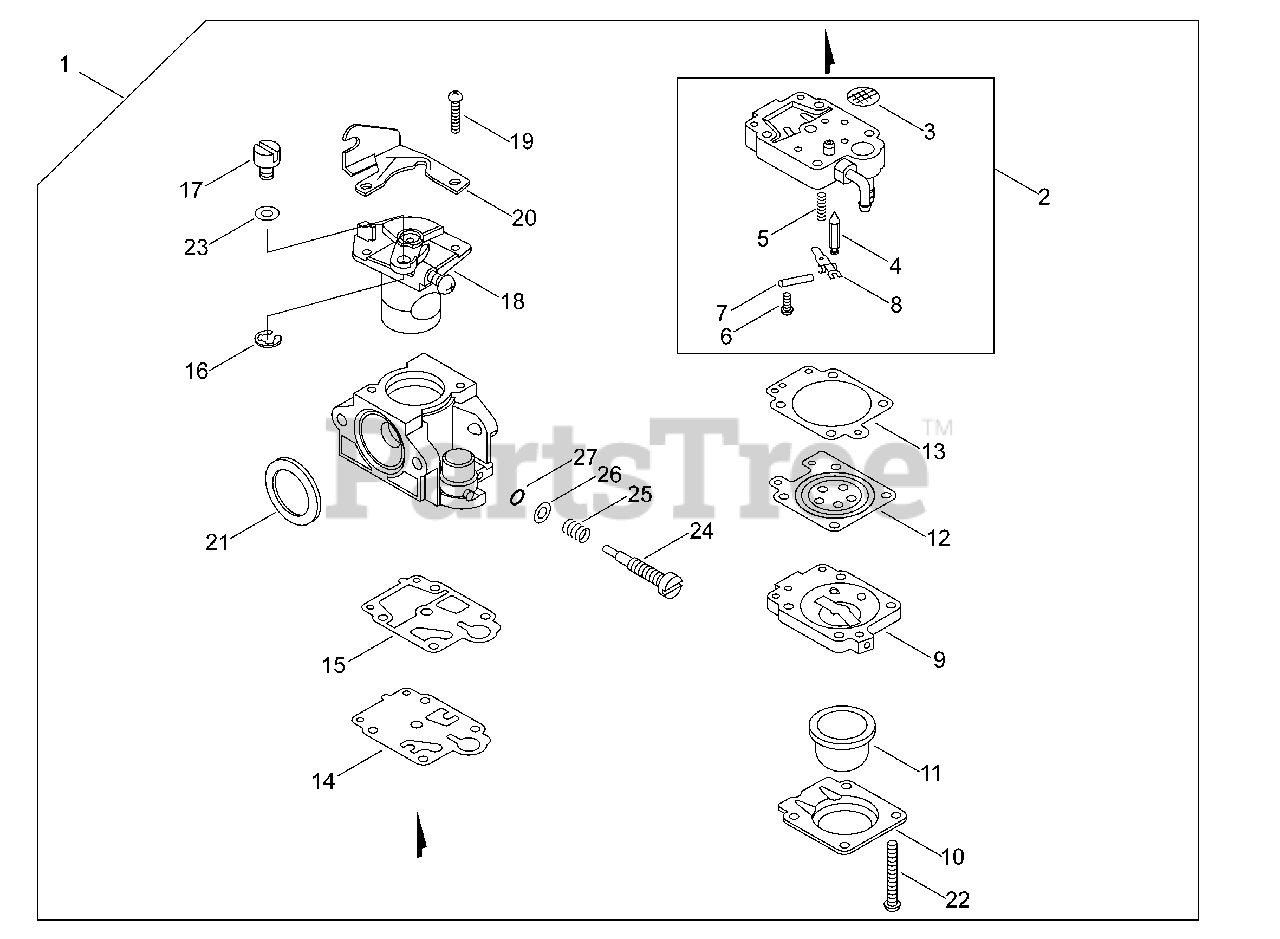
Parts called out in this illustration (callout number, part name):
1	CARBURETOR - WYK-496
2	+BODY ASSY, PUMP
3	++SCREEN, FUEL INLET
4	++VALVE, INLET NEEDLE
5	++SPRING, METERING LEVER
6	++SCREW
7	++PIN, METERING LEVER
8	++LEVER, METERING
9	+BODY ASSY, PURGE
10	+RETAINER, PURGE BULB
11	+BULB, PURGE
12	+DIAPHRAGM, METERING
13	+GASKET, METERING DIAPHRAGM
14	+DIAPHRAGM, PUMP
15	+GASKET, PUMP
18	+VALVE, THROTTLE
20	+BRACKET, THROTTLE CABLE
21	+RING, PACKING
24	+NEEDLE, MIXTURE
25	+SPRING, NEEDLE
26	+WASHER
27	+O-RING
